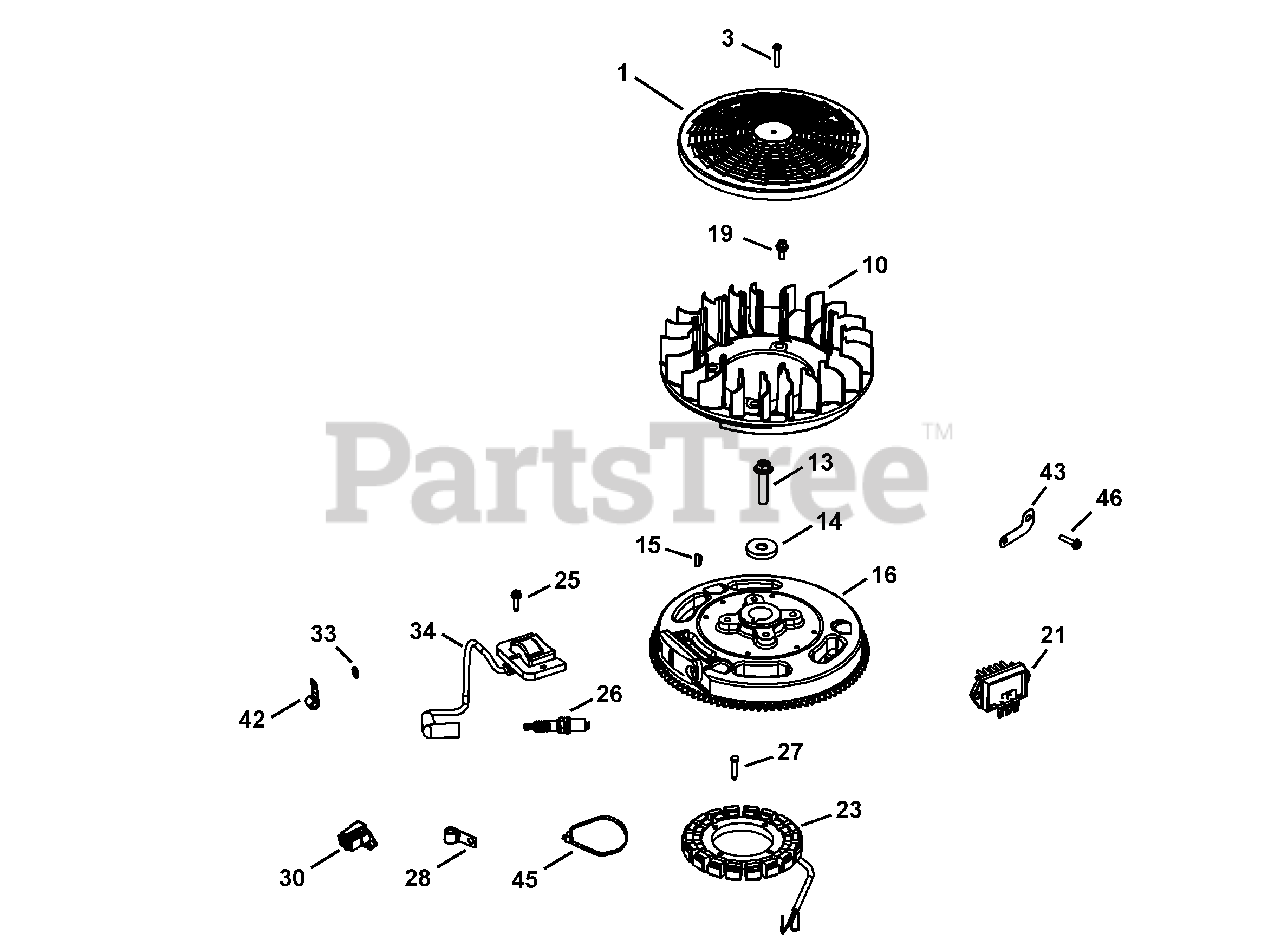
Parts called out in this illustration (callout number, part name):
3	Flange Screw, M4 x .7 x 25
13	Flange Screw, M10 x 1.5 x 45
14	Flat Washer, 13/32
15	Key, 3/16 x 5/8
16	Flywheel Assembly
19	Shoulder Bolt
21	Rectifier Regulator
23	15/20 Amp Stator Kit
25	Thread Forming Screw
26	Spark Plug
27	Thread Forming Screw
33	Flat Washer, 1/4"
34	Ignition Module Kit
43	Ground Strap Bracket
46	Hi-Lo Hex Flange Screw
